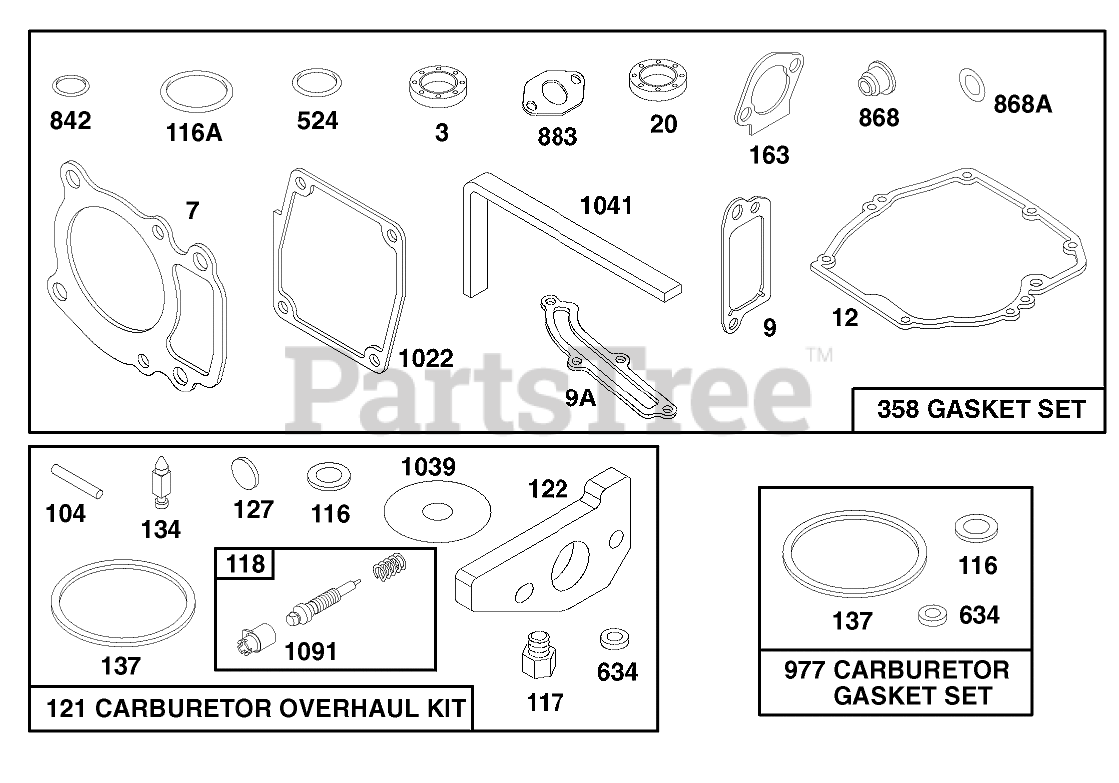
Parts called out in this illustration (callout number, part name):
3	SEAL - OIL
7	CYLINDER HEAD GASKET
9	BREATHER GASKET
9A	GASKET-BREATHER
12	ENGINE BASE GASKET
20	SEAL-OIL
104	FLOAT HINGE PIN
116	SEALING GASKET
116A	O RING SEAL
117	Jet-Main
118	VALVE/SPRING - NEEDLE
121	KIT-CARBURETOR OVERHAUL
122	ADAPTER ASSEMBLY
127	PLUG - WELCH
134	Valve-Inlet (Includes Seat)
137	FLOAT BOWL GASKET
163	AIR CLEANER GASKET
358	GASKET SET
524	O-RING
634	SEAL WASHER
842	O-RING
868	SealAssy-Valve
868A	Seal-Valve
883	EXHAUST GASKET
977	CARBURATOR GASKET SET
1022	ROCKER COVER GASKET
1039	FLOAT LIMITER
1041	SEAL - FOAM
1091	CAP - LIMITER
